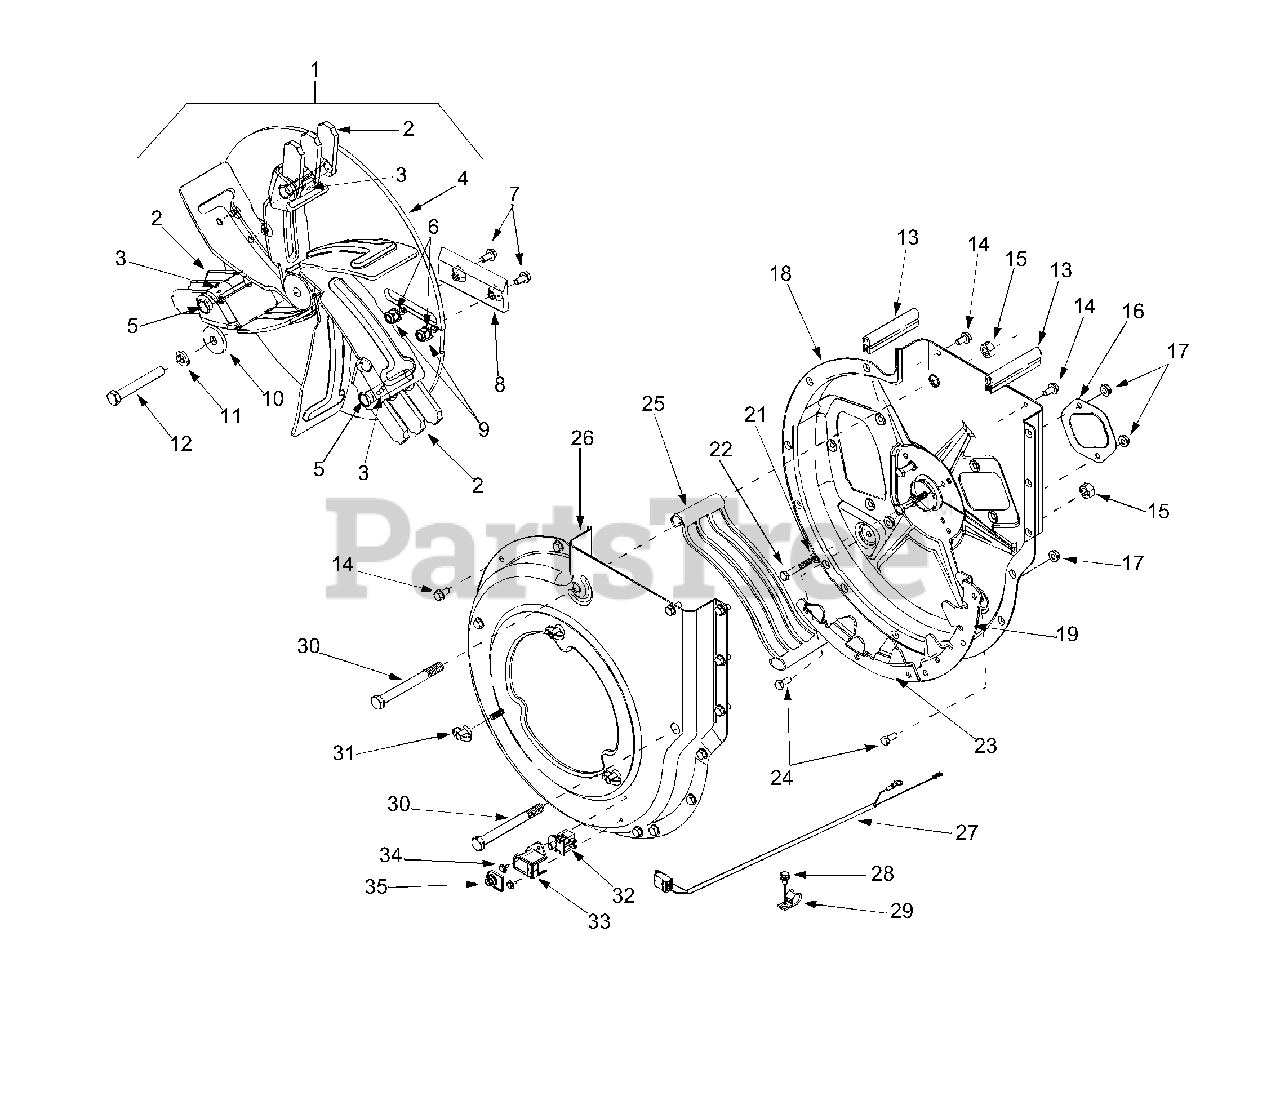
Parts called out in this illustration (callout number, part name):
1	Impeller Ass'y Complete
2	Flail Blade
3	Spiral Pin
4	Impeller Assembly
5	Clevis Pin
6	Lock Washer 5/16
7	Cap Screw 5/16-24 x 1.0
8	Chipper Blade
9	Hex Lock Nut 5/16-24
10	Flat Washer .406 x 1/1/4
11	Lock Washer 3/8
12	Hex Cap Screw 3/8-24 x 2.75
13	Rubber Seal
14	Hex Washer Screw 5/16-18
15	Hex Lock Nut 1/2-13
17	Hex Flange Lock Nut 5/16-18
19	Upper Shredder Blade
21	Lock Washer 5/16
22	Hex Cap Screw 5/16-18 x 2
23	Flail Housing Blade
24	Hex Cap Screw 5/16-18 x .75
25	Discharge Screen
27	Wire Harness
28	Hex Washer Screw 1/4-14
29	Clamp
30	Hex Cap Screw 1/2-13 x 5.0
31	Knob 5/16-18
32	Switch
33	Safety Switch Mounting Cover
34	Hex Washer Screw
35	Switch Cover
